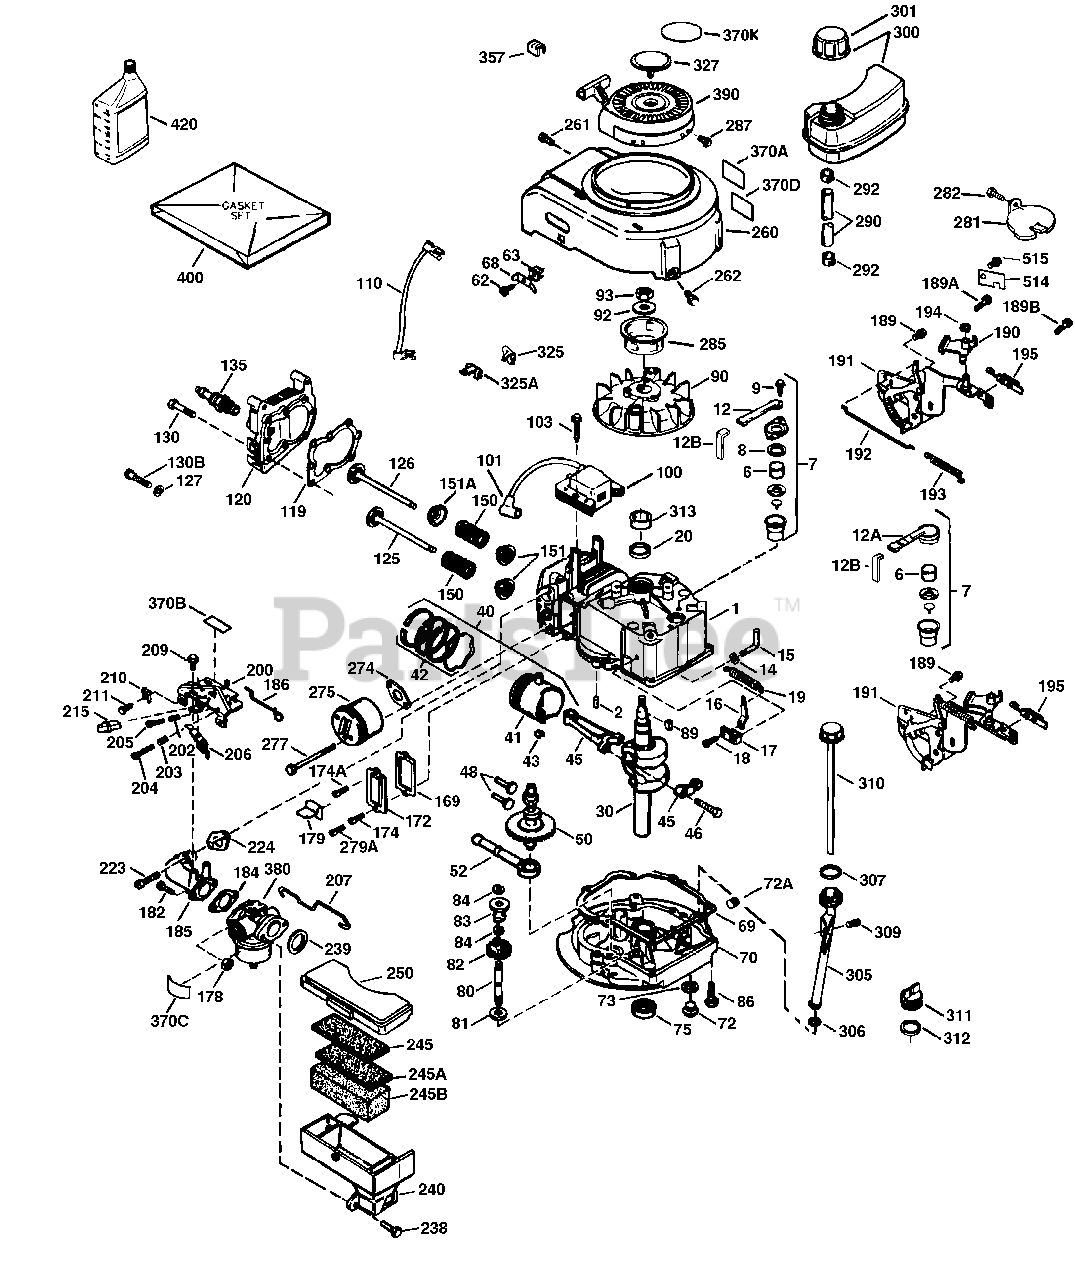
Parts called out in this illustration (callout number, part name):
1	"Cylinder Incl. 2,7,20,125,169,172,174
2	Dowel Pin
6	Breather Element
7	Breather Ass'y. (Incl. 6 & 12A)
12	Breather Tube
12A	Breather Cover & Tube (Incl. 12B)
12B	Breather Tube Elbow
14	Flat Washer
15	Governor Rod (Incl. 14)
16	Governor Lever
17	Governor Lever Clamp
18	Screw, Torx T-15, 8-32 x 19/64"
19	Extension Spring
20	Oil Seal
30	Crankshaft
40	Piston, Pin & Ring Set (Std.)
40	Piston, Pin & Ring Set (.010" OS)
40	Piston, Pin & Ring Set (.020" OS)
41	Piston & Pin Ass'y. (Std.) (Incl. 43)
41	Piston & Pin Ass'y. (.010" OS) Incl. 43
41	Piston & Pin Ass'y. (.020" OS) Incl. 43
42	Ring Set (Std.)
42	Ring Set (.010" OS)
42	Ring Set (.020" OS)
43	Piston Pin Retaining Ring
45	Connecting Rod Ass'y. (Incl. 46)
46	Connecting Rod Bolt
48	Valve Lifter
50	Camshaft (BCR)
52	Oil Pump Ass'y.
69	* Mounting Flange Gasket
70	Mounting Flange (Incl.72 thru 83,306)
72	Oil Drain Plug
75	Oil Seal
80	Governor Shaft
82	Governor Gear Ass'y. (Incl. 81)
83	Governor Spool
86	Screw, 1/4-20 x 1-1/4"
89	Flywheel Key (also available in Packa ged Part #740007B)
90	Flywheel
92	Belleville Washer
93	Flywheel Nut
100	Solid State Ignition
101	Spark Plug Cover
103	Screw, Torx T-15, 10-24 x 15/16"
110	Ground Wire
119	* Cylinder Head Gasket
120	Cylinder Head (Incl. 119)
125	Exhaust Valve (Std.) (Incl. 151)
125	Exhaust Valve (1/32" OS) (Incl. 151)
126	Intake Valve (Std.) (Incl. 151)
126	Exhaust Valve (1/32" OS) (Incl. 151)
130	Screw, 5/16-18 x 1-1/2"
135	Resistor Spark Plug (RJ19LM) also ava ilable in Packaged Part #740081
150	Valve Spring
151	Valve Spring Cap
169	* Valve Cover Gasket
172	Valve Cover
174	Screw, 10-24 x 9/16"
178	Nut & Lock Washer 1/4-28
179	Retainer Clip
182	Screw, 1/4-28 x 7/8"
184	* Carburetor To Intake Pipe Gasket
185	Intake Pipe
186	Governor Link
189	Screw, Torx T-30, 1/4-20 x 3/8"
200	Control Bracket (Incl. 202 thru 206)
202	Compression Spring
203	Compression Spring
204	Screw, Torx T-10, 5-40 x 7/16"
205	Screw, Torx T-10, 6-32 x 41/64"
206	Terminal
207	Throttle Link
209	Screw, 10-24 x 9/16"
210	Conduit Clip
211	Screw, 10-32 x 3/8"
223	Screw, 1/4-20 x 1"
224	* Intake Pipe Gasket
238	Screw, 10-32 x 49/64"
239	* Air Cleaner Gasket
245	Air Filter (Paper) (also available in Packaged Part #740095 (Qty.2))
250	Air Cleaner Cover
260	Blower Housing
261	Screw, 10-24 x 9/16"
262	Screw, 1/4-20 x 1/2"
275	Muffler (Incl. 277)
277	Screw, 1/4-20 x 2-5/16"
278	Spacer
285	Starter Cup
287	Screw, 8-32 x 21/64"
290	Fuel Line
292	Fuel Line Clamp
300	Fuel Tank (Incl. 292 & 301)
301	Fuel Cap
305	Oil Fill Tube
306	* "O"-Ring
307	"O" Ring
309	Screw, 10-32 x 1/2"
310	Dipstick
370A	Lubrication Decal
370C	Decal - Primer 5X with Hand
370K	Starter Decal
380	Carburetor (Incl. 184)
390	Rewind Starter (NOTE: This engine co uld have been built with 590738 start er).
400	* Gasket Set (Incl. items marked PK in notes) Incl. part #'s 26756 (1),27234 A (1), 33735 (1), 34338 (1),34690A (1 ), 36437 (1), 36832 (1),36996 (1), 37 130 (1)
420	SAE 30 4-Cycle Engine Oil (1 Quart)
999	Summer Maintenance Kit (incl. Oil, Sp ark Plug, Air Cleaners (2), & Ultra-F resh)
